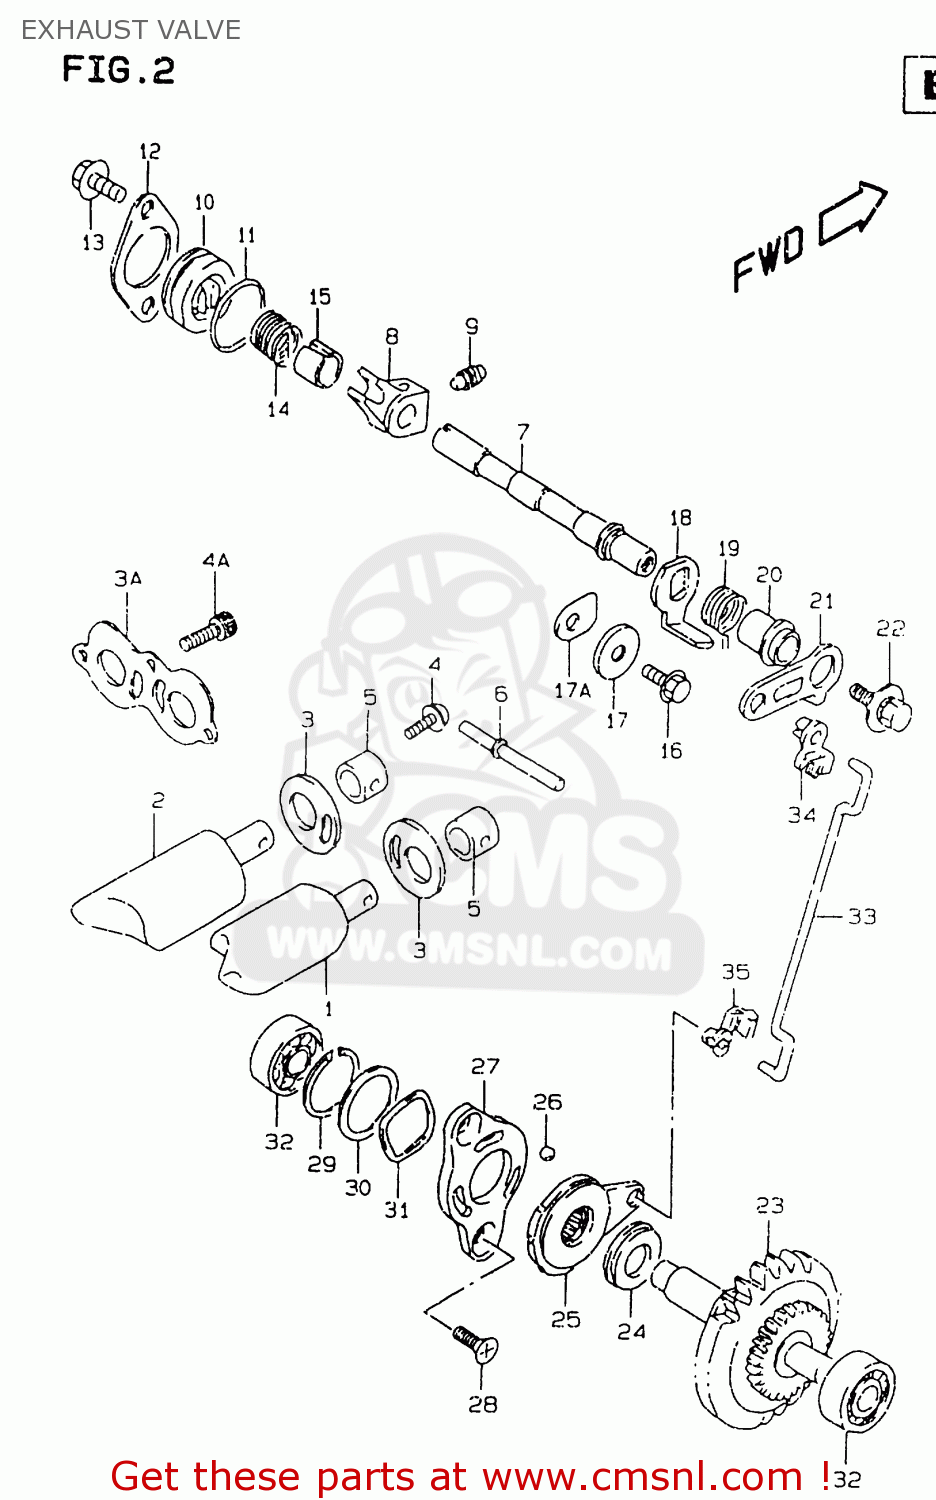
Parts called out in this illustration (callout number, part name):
1	VALVE,EXHAUST,R
2	VALVE,EXHAUST,L
3	PLATE,EXHAUST VALVE
3A	PLATE,EXHAUST VALVE
4	SCREW 5X12
4A	BOLT
5	SPACER,EXHAUST VALVE
6	PIN,EXHAUST VALVE
7	SHAFT,EXHAUST VALVE
8	ARM,EXHAUST VALVE SHAFT
9	SCREW(6X10)
10	CAP,EXHAUST VALVE
11	O RING(D:1.9,ID:22.6)
12	RETAINER,EXHAUST VALVE
13	BOLT
14	SPRING
15	SPACER,EXHAUST VALVE SPRING
16	BOLT
17	WASHER
17A	RETAINER
18	LEVER,EXHAUST VALVE NO.2
19	SPRING
20	SPACER,EXHAUST VALVE
21	LEVER,EXHAUST VALVE NO.1
22	BOLT(5X12)
23	GOVERNOR ASSEMBLY,EXHAUST
24	BEARING(10X22X2.8)
25	ACTUATOR,EXHAUST VALVE
26	BALL
27	STARTER,EXHAUST VALVE ACTUATOR
28	SCREW(5X10)
29	CIRCLIP
30	SHIM(19.1X25X0.3)
31	WASHER
32	BEARING(8X22X7)
33	ROD,EXHAUST VALVE
34	BUSH,EXHAUST VALVE ROD NO.1
35	BUSH,EXHAUST VALVE ROD NO.2
